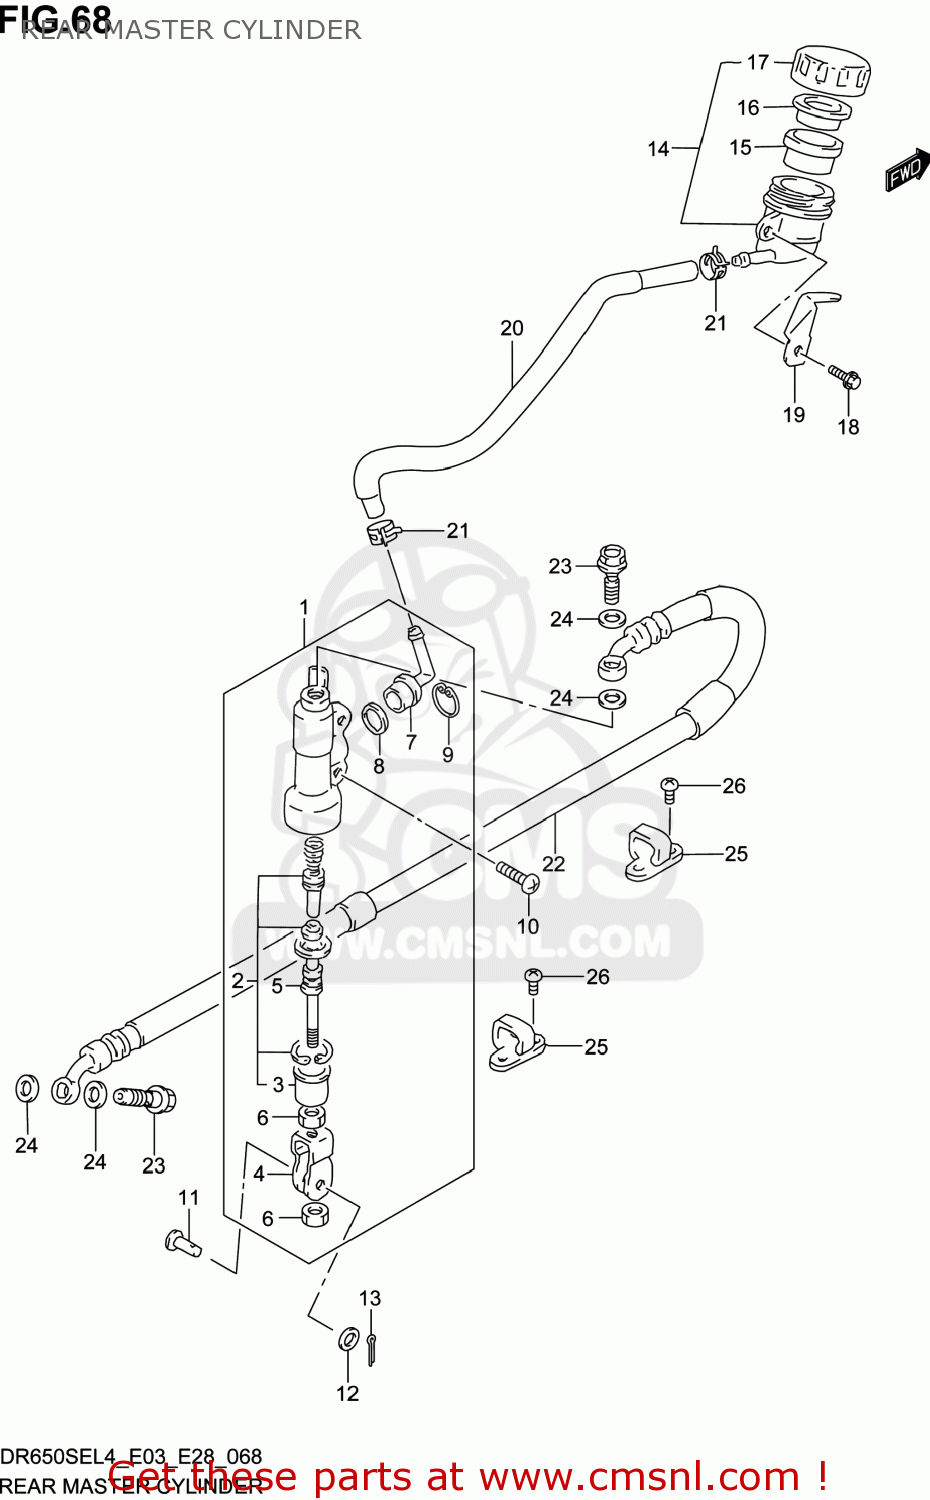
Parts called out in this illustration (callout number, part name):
1	CYLINDER ASSY,RR MASTER
2	PISTON/CUP SET
3	BOOT
4	YOKE
5	ROD,PUSH
6	NUT
7	CONNECTOR
8	O RING
9	CIRCLIP
10	SCREW(6X16)
11	PIN(8X20)
12	WASHER(8.5X14X1.6)
13	PIN
14	TANK ASSY,RR BRAKE RESERVOIR
15	DIAPHRAGM
16	PLATE
17	CAP
18	BOLT
19	GUARD,RSVR TANK CAP
20	HOSE,RESERVOIR TANK
21	CLIP
22	HOSE,RR BRAKE
23	BOLT UNION
24	WASHER(10X15X1.5)
25	GUIDE,RR BRAKE
26	SCREW
